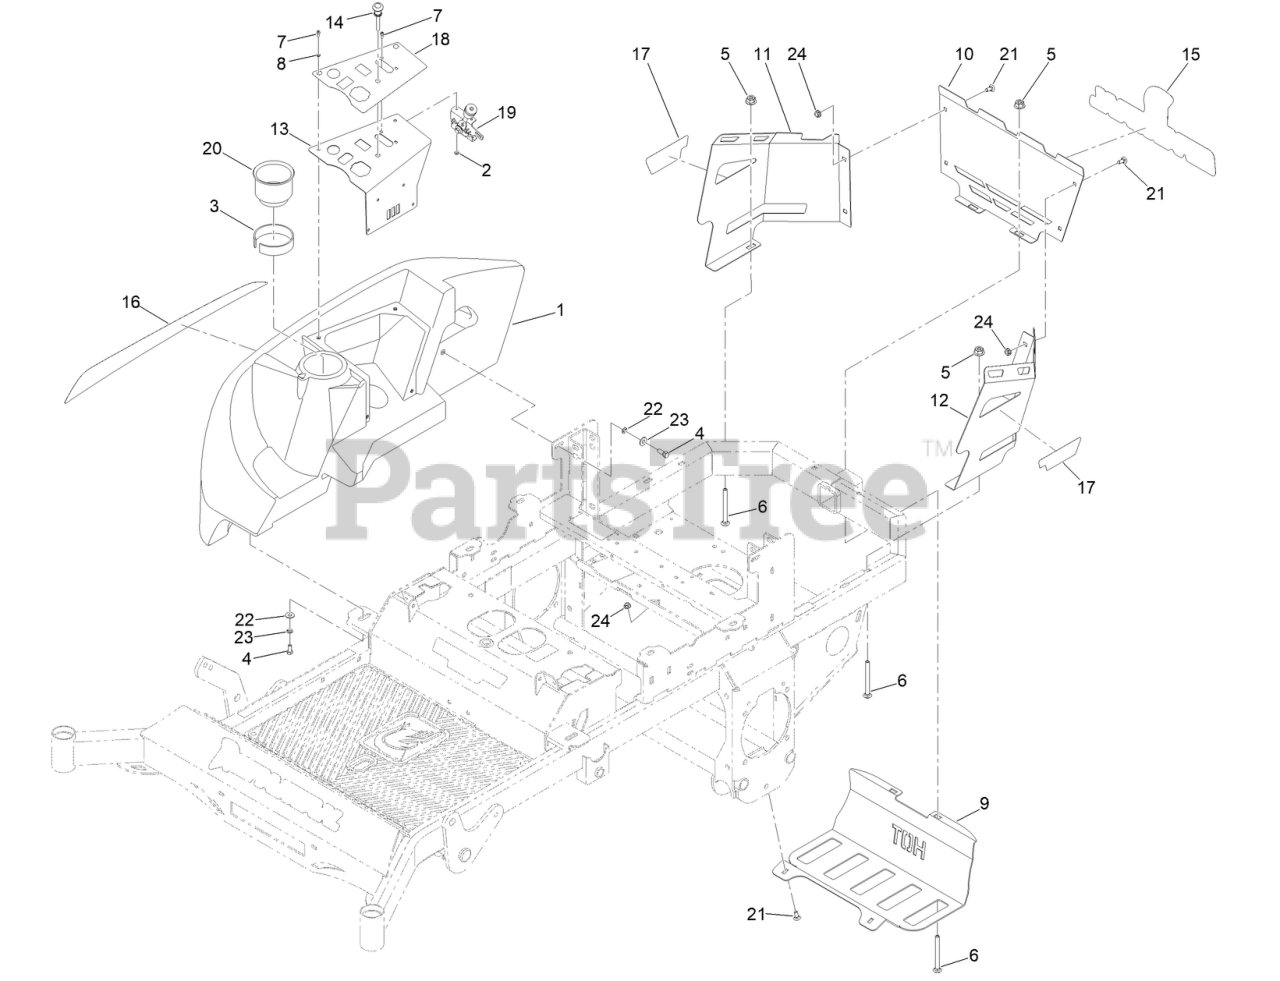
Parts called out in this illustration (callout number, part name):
1	CONSOLE W/ CUPHOLDER
2	NUT-LOCK
3	TAPE-FOAM
4	SCREW-HH
6	3/8-16 X 4 CARRIAGE BOLT ZINC
7	10-24 X 1/2 SOCKET C/S 18-8 SS
8	#10 SPLIT LOCKWASHER 18-8 SS
9	MWR MUFFLER GUARD PAINT
10	PLATE - ENGINE COWLING
11	2021 RT/SRT ENGN COWLING RTPAINTED
12	2021 RT/SRT ENGN COWLING LT PAINTED
13	CONTROL PANEL BRKT INDIV CONTROLS PAINT
14	MWR CHOKE CABLE ASSM
15	MWR RR SPARTAN LOGO
16	MWR FUEL TANK LOGO RT SIDE
17	RT-HD MODEL DECAL
18	RZ-HD/RT/SRT/KGZ-XDE KEYSWTCH CONSL DECL
19	ENVY/FX1000 THROTTLE CABLE
20	CUP HOLDER
21	BOLT-CARR
22	WASHER-LOCK
23	WASHER-FLAT
